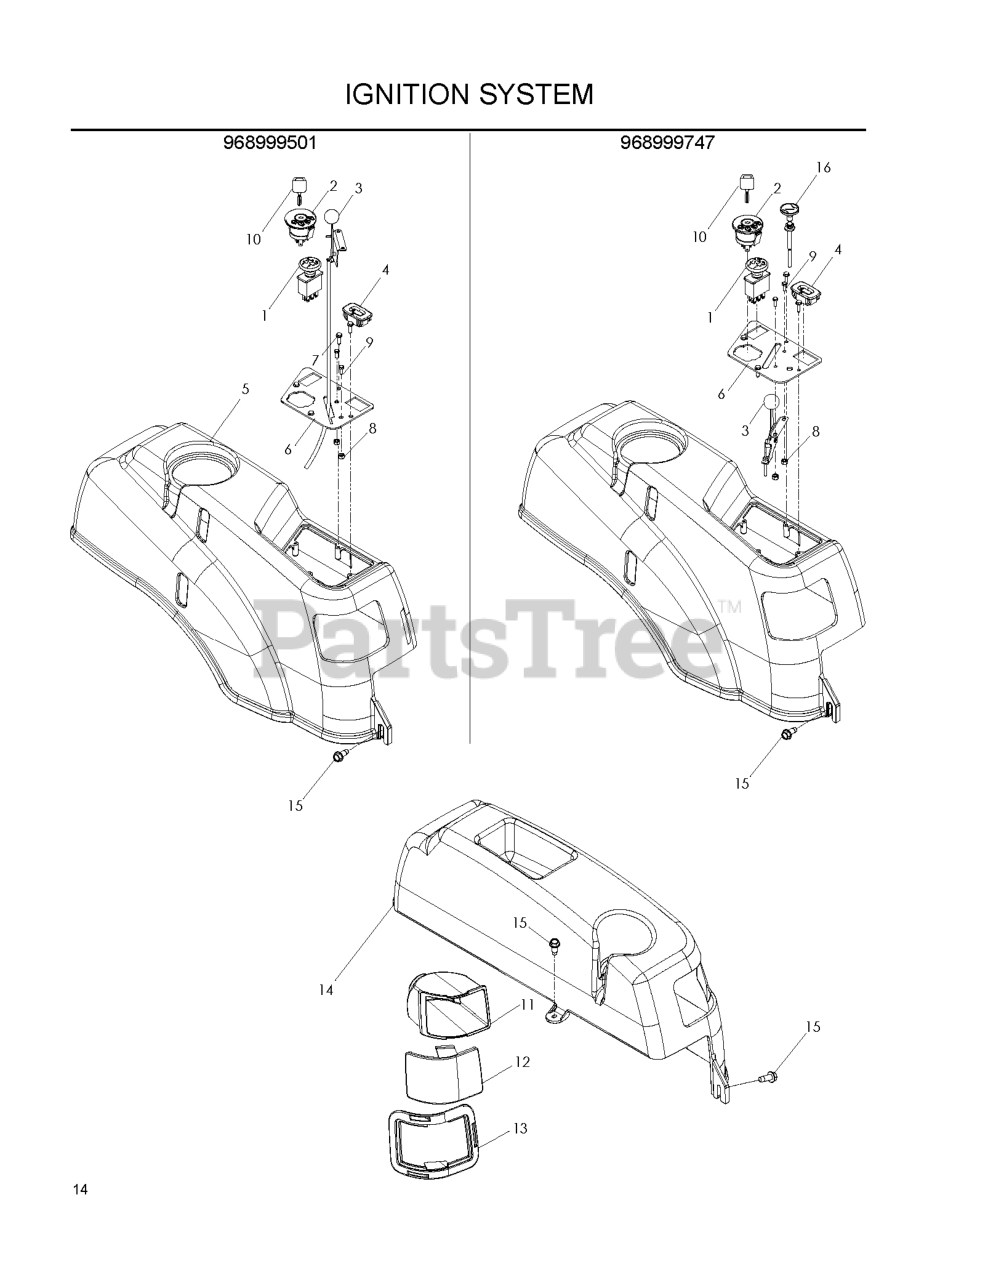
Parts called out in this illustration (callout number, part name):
1	RP.SWITCH, BLADE
2	RP IGNITION SWITCH
3	THROTTLE CABLE DETENT
3	THROTTLE CABLE
4	HOUR METER
5	RP.FENDER, RT
6	PLATE.CONTROL.CONSOLE.BLACK
6	CONSOLE.PLATE.BLACK
7	SCR #10-12X3/4 HEX WAS HD ZD
8	NUT 10-24 NYLOC
9	HCS #10-24 X 1/2
10	KEY
11	RT HEADLIGHT REFLECTOR
11	LEFT HEADLIGHT REFLECTOR
12	LENS, COLORED LEFT
12	LENS, COLORED RIGHT
13	RT HEADLIGHT RIM GREY
13	LEFT HEADLIGHT RIM GREY
14	FENDER, LT
15	SCREW 1/4 X 5/8
16	CHOKE CONTROL
